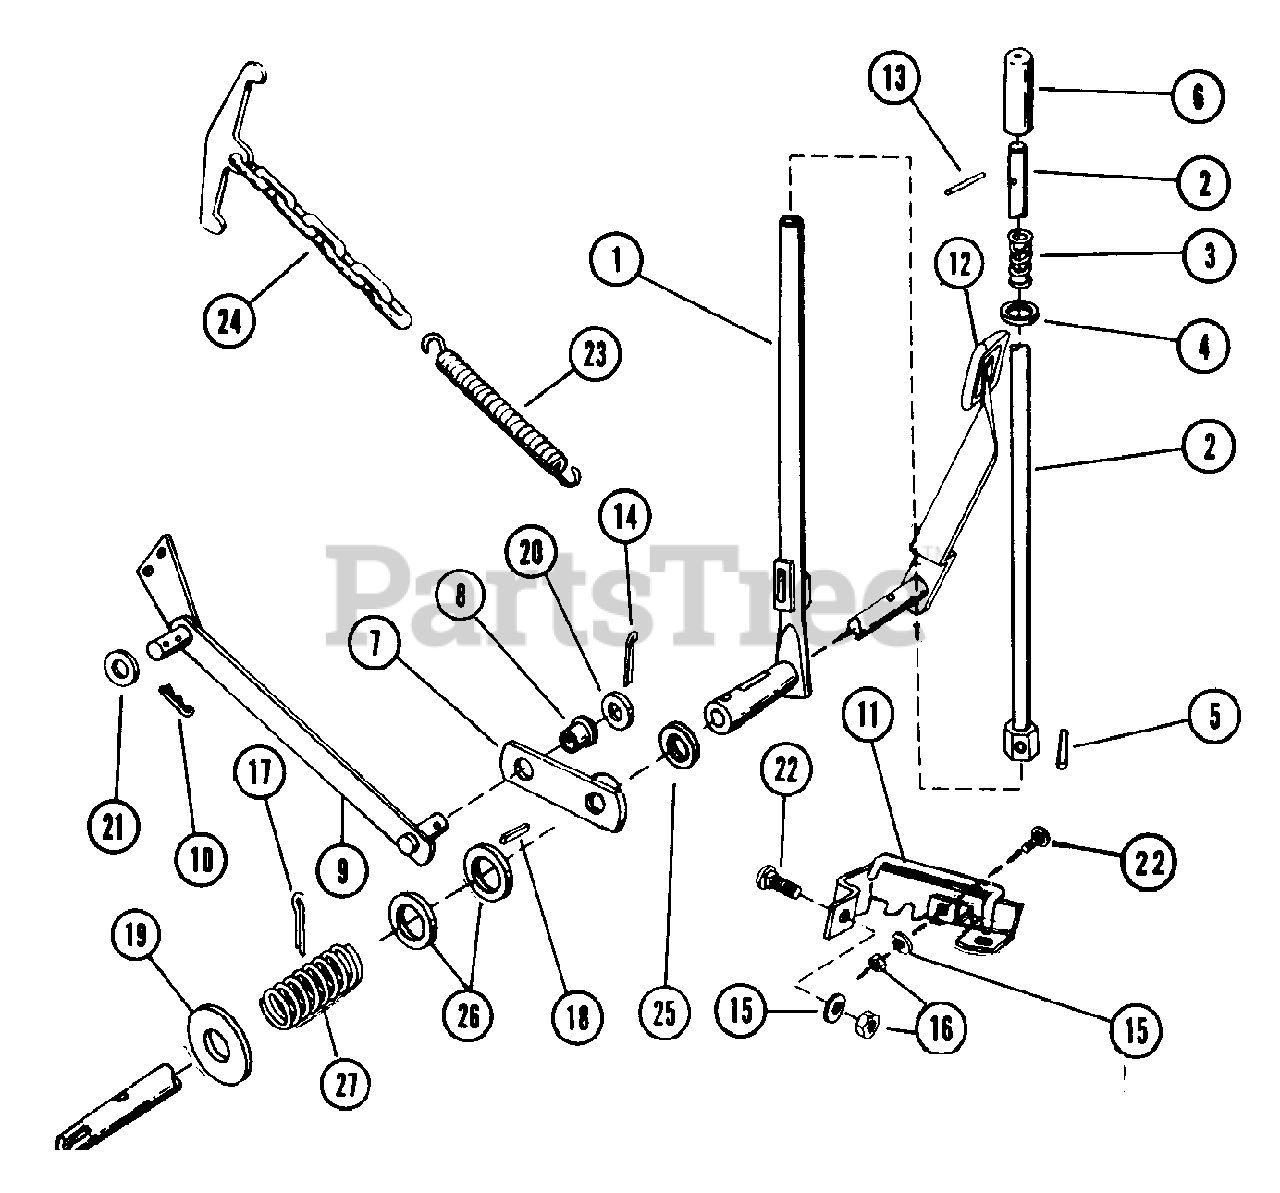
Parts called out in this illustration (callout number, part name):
1	LIFT HANDLE SERVICE ASSEMBLY
3	SG-COMP .048X.59X2.06 WLD9
4	WSHR-FL-STL .458X.750X.06 PL
5	PIN-ROLL .375X2.50
8	BSHG-FLG .625X.687X.437X.937
9	LIFT LEVER
10	PIN-HAIR INT .09X.188 PL
11	QUADRANT
12	L.H. LEVER
13	PIN-ROLL .125X.75
14	PIN-COTR .18X1.0 PL
15	WSHR-LK .375X.094 MED PL
16	NUT-HEX .375-16
17	PIN-COTR .18X1.25 PL
18	KEY-SQ .188X1.0X.188 SAE 8630
19	WSHR-FL-STL .755X2.000X.125
20	WSHR-FL-STL.656X1.312X.095 PL
21	WSHR-FL-STL.812X1.500X.139
22	BLT-RDHDSQSHNK .38-16X1.00 PL
23	SG-TENS .156X1.062X8.68 WLD ??
25	BSHG-FLG 1.375X1.75X.875X2.125
26	WSHR-FL-STL .755X1.375X.062 PL
27	SG-COMP .148X1.23X2.53 WLD87
